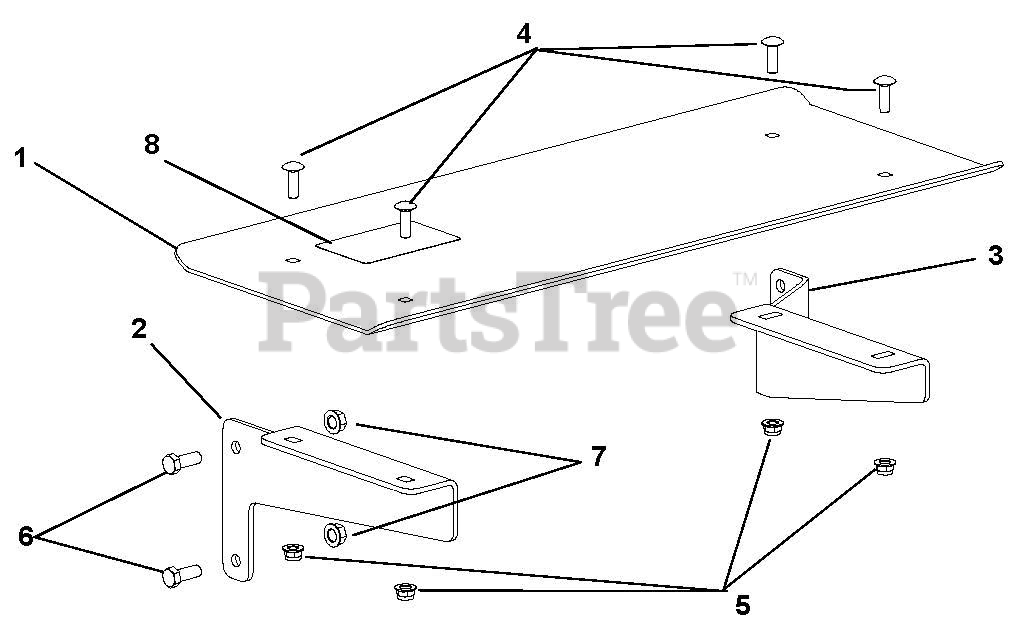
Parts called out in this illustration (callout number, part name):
1	TABLE, WORK - LOG SPLITTER
2	BRKT, FRONT - WORK TABLE
3	BRKT, REAR - WORK TABLE
4	@BLT-RHDSSQNK .31-18X1.00 G5YZ
5	@NUT-LK-NYL-FLG .31-18 YWZC
6	@BLT-HEX .38-16X1.00 GR5 YWZC
7	@NUT-LK-TOP-FLG .38-16 YWZC
8	DECAL,SPLITTER TABLE
